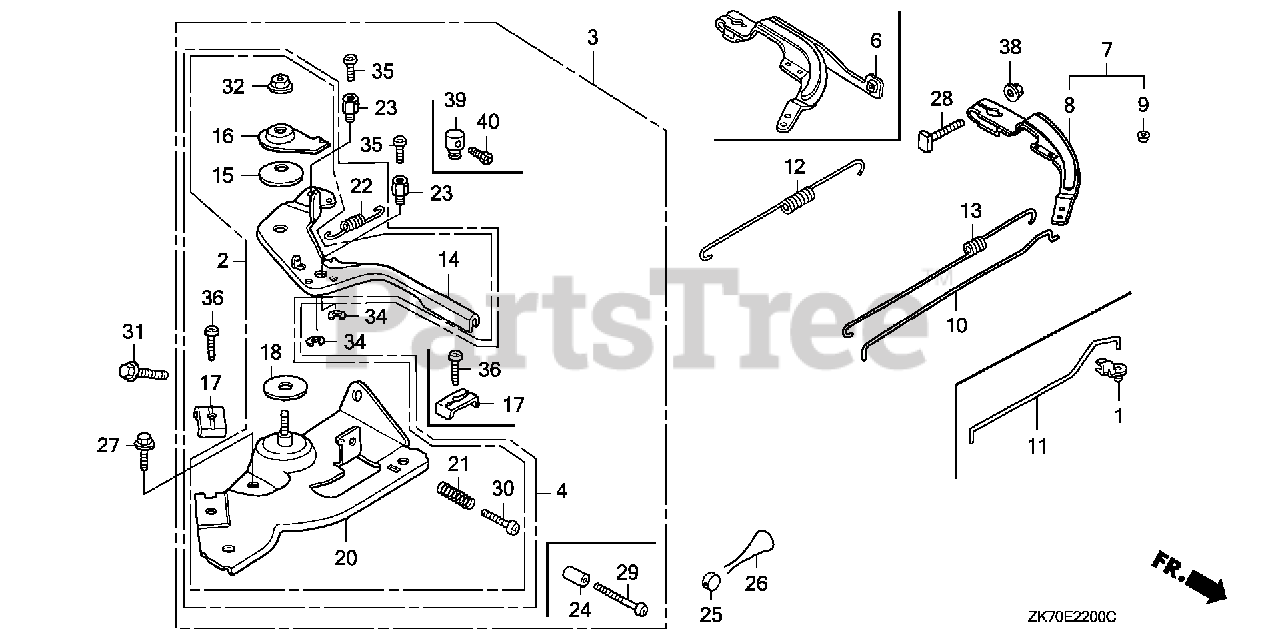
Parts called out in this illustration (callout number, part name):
3	CONTROL ASSY. (REMOTE)
8	ARM, GOVERNOR
10	ROD, GOVERNOR
12	SPRING, GOVERNOR
13	SPRING, THROTTLE RETURN
14	LEVER, CONTROL
15	SPRING, LEVER
16	WASHER, CONTROL LEVER
17	HOLDER, CABLE
18	SPACER, CONTROL LEVER
20	BASE, CONTROL
21	SPRING, CONTROL ADJUSTING
22	SPRING, CABLE RETURN
23	HOLDER, WIRE
27	BOLT, FLANGE (6X12) (CT200)
28	BOLT, GOVERNOR ARM
30	SCREW, PAN (5X25)
31	BOLT, FLANGE (6X20) (CT200)
32	NUT, SELF-LOCK (6MM)
34	CIRCLIP (5MM)
35	SCREW, PAN (4X6)
36	SCREW, PAN (5X16)
38	NUT, FLANGE (6MM)
